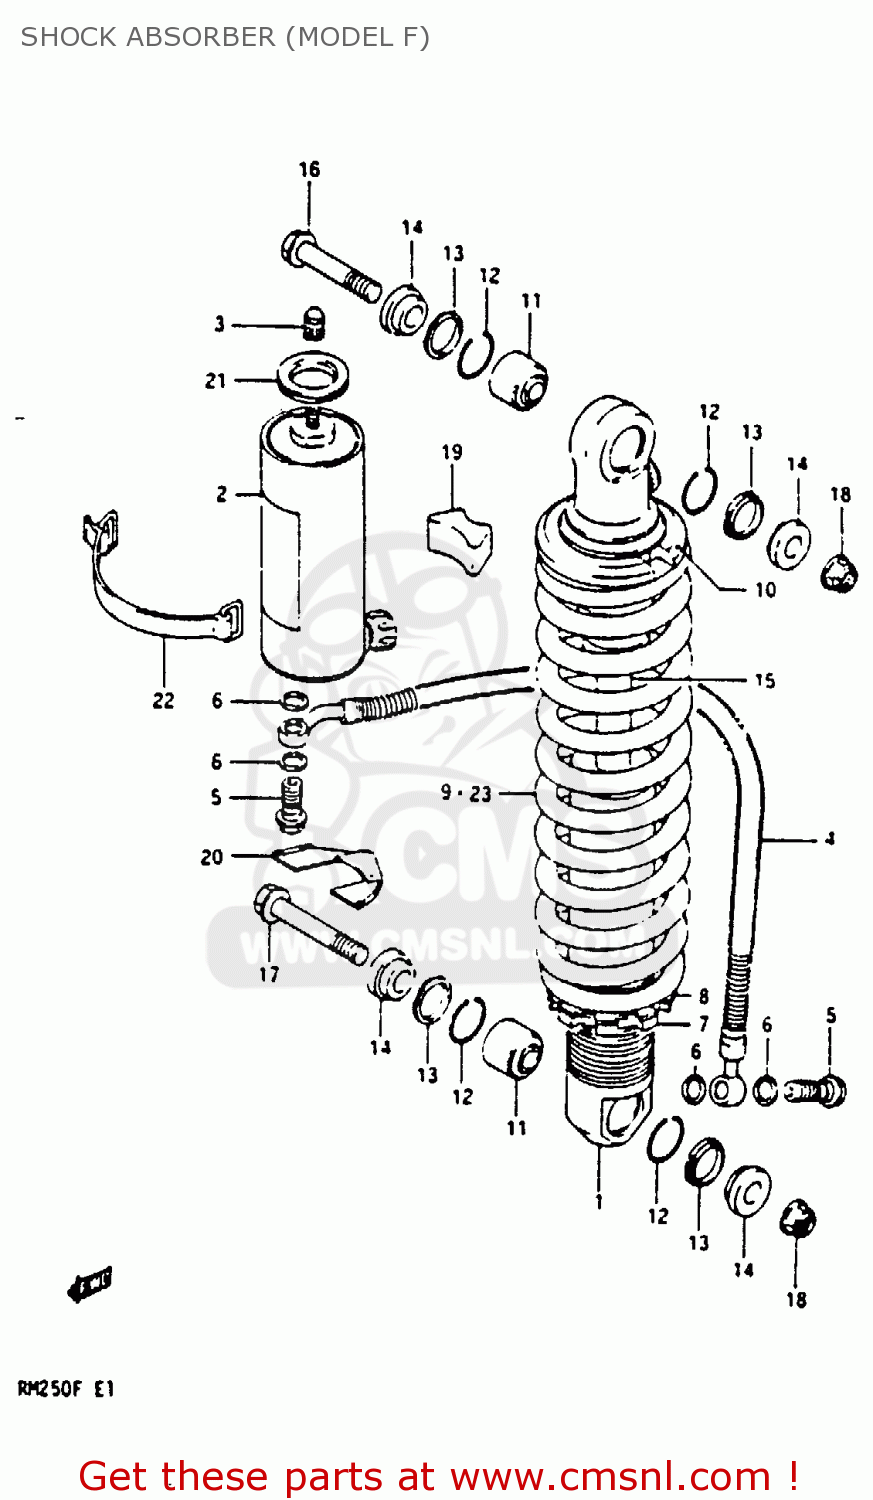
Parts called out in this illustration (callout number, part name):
1	SHOCK ABSORBER ASSY, REAR (BLUE)
2	RESERVE TANK,REAR SHOCK
3	CAP
4	HOSE,REAR SHOCK ABSORBER
5	BOLT,REAR SHOCK ABSORBER
6	GASKET (NAS)
7	GUIDE,REAR SHOCK ABSORBER SPRING
8	GUIDE,SPRING
9	SPRING
10	GUIDE,REAR SHOCK ABSORBER SPRING
11	BEARING,REAR SHOCK ABSORBER
12	RING
13	SEAL,DUST RR SHOCK ABSORBER
14	COLLAR
15	ROD, PISTON
16	BOLT,REAR SHOCK ABSORBER
17	BOLT(10X52)
18	NUT
19	CUSHION,RESERVOIR TANK
20	CUSHION,RESERVOIR TANK
21	CUSHION,RESERVOIR TANK
22	BAND
23	SPRING
